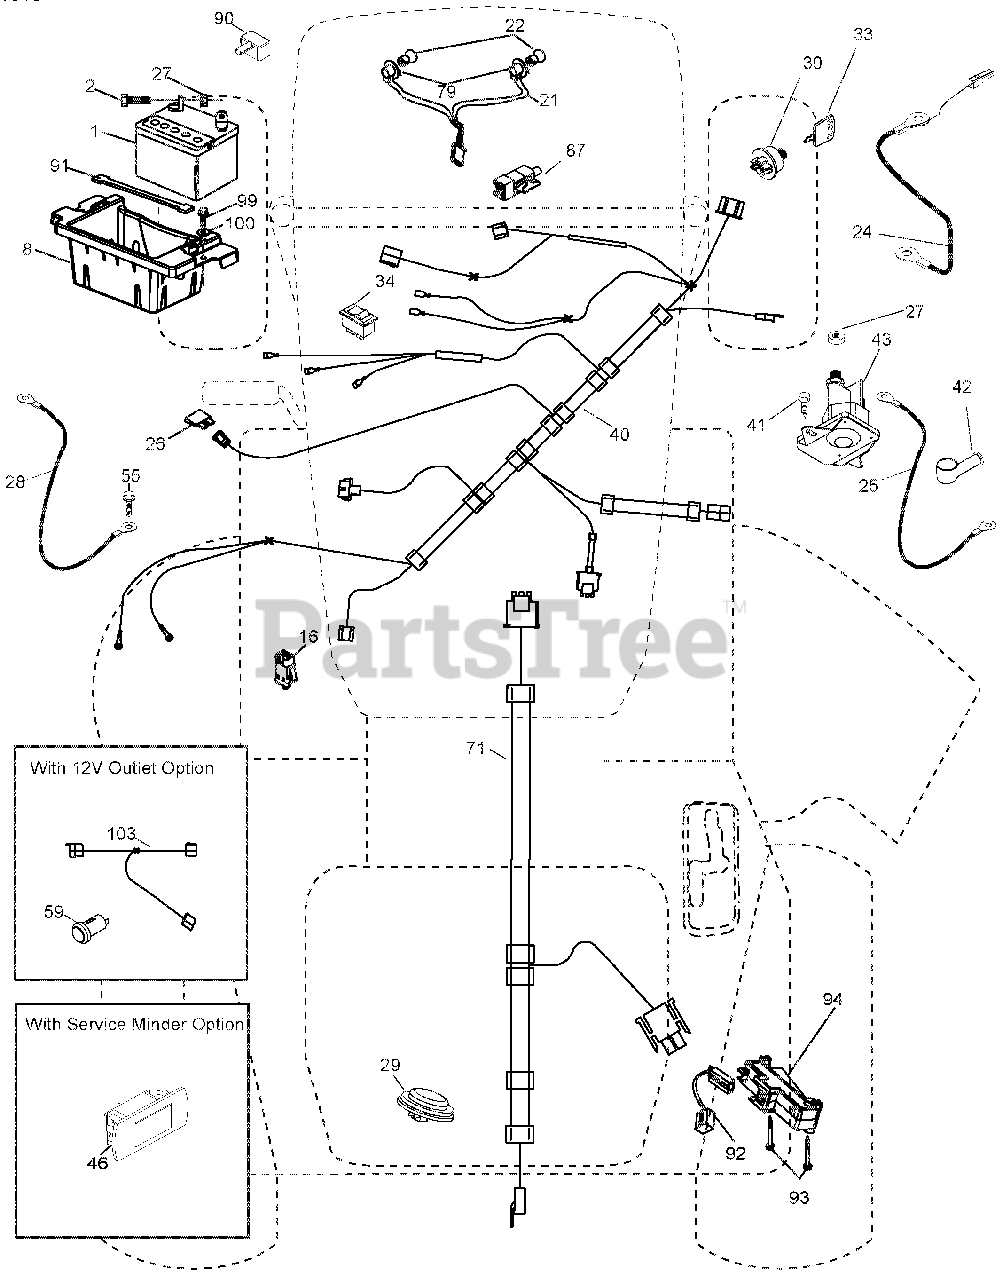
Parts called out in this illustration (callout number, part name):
1	BATTERY.12.VOLT.28.AMP.WET
2	BOLT.HEX.HD.1/4-20UNC X 3/4
8	BOX.BATTERY.MOUNT.FRONT.LT
16	SWITCH.INTERLOCK.NONO.GRAY
21	HARNESS ASM.LIGHT.22"(4152J)
22	BULB.LIGHT.#1156
24	CABLE.BTRY.PSWRE.DSH SOL.8"TEX
25	CABLE.STARTER.6GA.BL/RED.14.5"
26	FUSE.20 AMP.
27	Nut, Keps Hex 1/4-20 unc
28	CABLE.GROUND.21"BLK.6 GA.90T
29	SWITCH.SEAT.DELTA.OPC.9LB.
30	SWITCH.IGN.DLTA.P-IN.ROS
33	KEY/CHAIN.BLISTER PACK.GEN.CE
34	SWITCH.LIGHT/RESET.B/B/RED.
40	HARNESS.IGN.DASH.CBL.YTGT.PRED
41	Screw 1/4-20 x 1/2
42	COVER.TERMINAL.RED
43	SOLENOID.W/BRASS PLUNGER.2005
55	SCREW.5/16-18X3/4.SMGML.TAP/R
71	HARNESS.IGN.CHASSIS.TEX
79	SOCKET ASM.BULB.TWISTLOCK
87	SWITCH.INTRLCK.CLUTCH.CABLE.TX
90	COVER.TERMINAL.BATTERY.FR.TEX
91	STRAP.BATTERY.MOUNT.FRONT
92	HARNESS.PIGTAIL.CONSLE.ROS.MLK
93	SCREW.PLASTITE.10-14 X 2.0
94	MODUAL REVERSE ROS
99	SCREW.HEXWSH.THDROL.1/4-20X3/4
100	WASHER.9/32 X 7/8 X 16GA.
